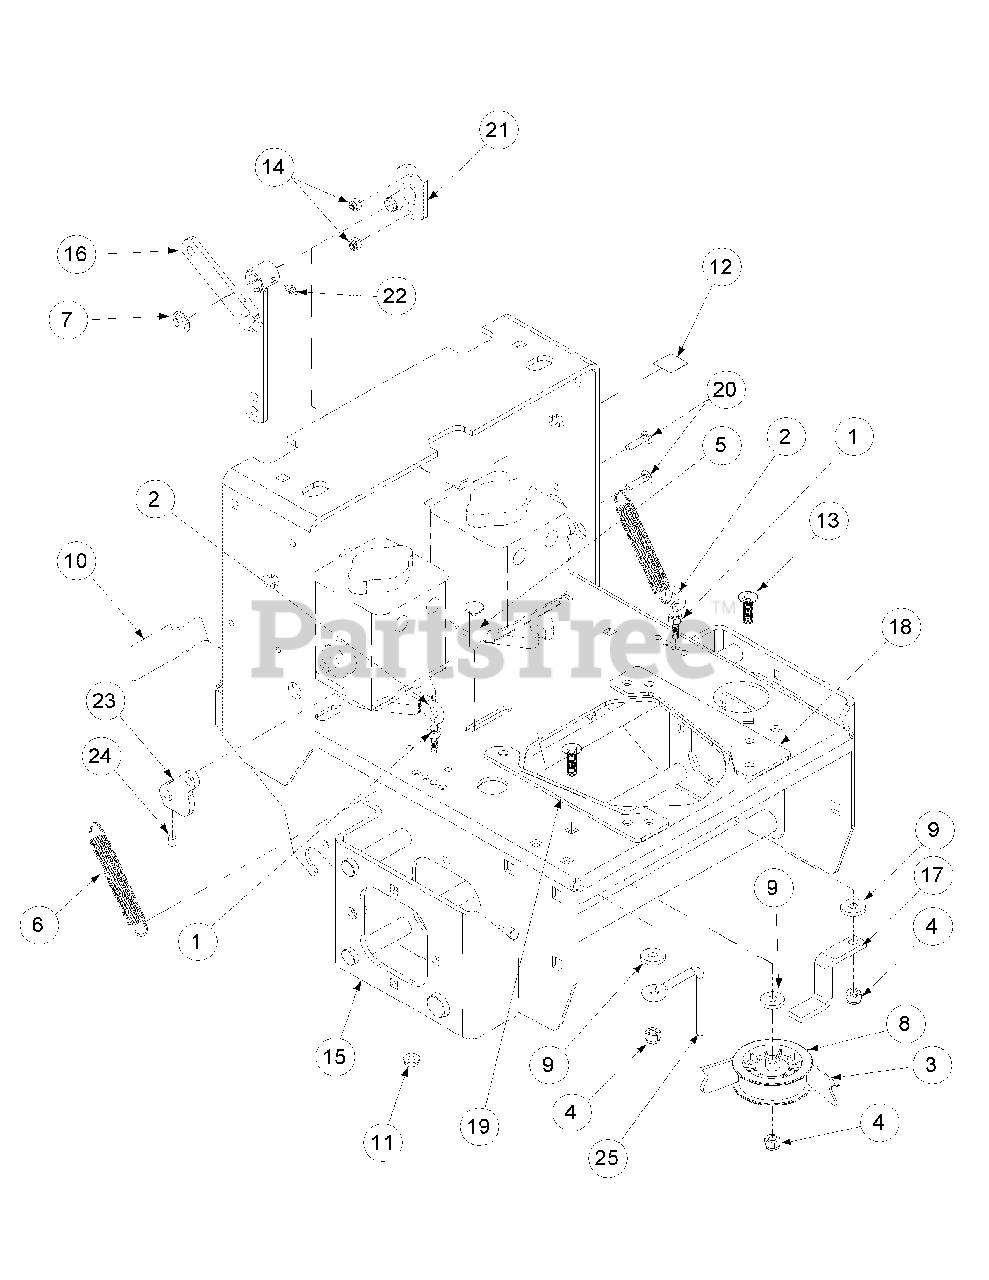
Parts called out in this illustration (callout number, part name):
1	Hex Nut, 5/16-18
3	Belt, Hydro Pump
4	Nut, L, Nylon Insert, 3/8-16 Grade A
5	Carriage Bolt, 3/8-16 x 2 Grade 5
6	Spring, Music Wire, LE-093G-9, Plated
7	E-Ring, 5/8" #5113-62
8	Pulley, Flat Idler W/Adaptor
9	Washer, Idler
10	Decal, "Made In America"
11	Lock Nut, 5/16-18, Hex Flange Lock
12	Label, Mower, Warn, Open Belt Drive
13	Carriage Bolt, 3/8-16 x 1.25 Grade 5
14	Nut, L, Nylon Insert, 1/4-20 Grade A
15	Engine Base Assembly
16	Bellcrank Clutch
17	Belt Guide, Engine, 36/42/48
18	Spacer, Engine, LH
19	Spacer, Engine, RH
20	Carriage Bolt, 1/4-20 x 1.00
21	Bellcrank Pivot Weldment
22	Grease Fitting, 1/4-28 x 3/16
23	Hydro Pump Lever
24	Set Screw, 5/16-24 x .50
25	Belt Guide, 3.375
